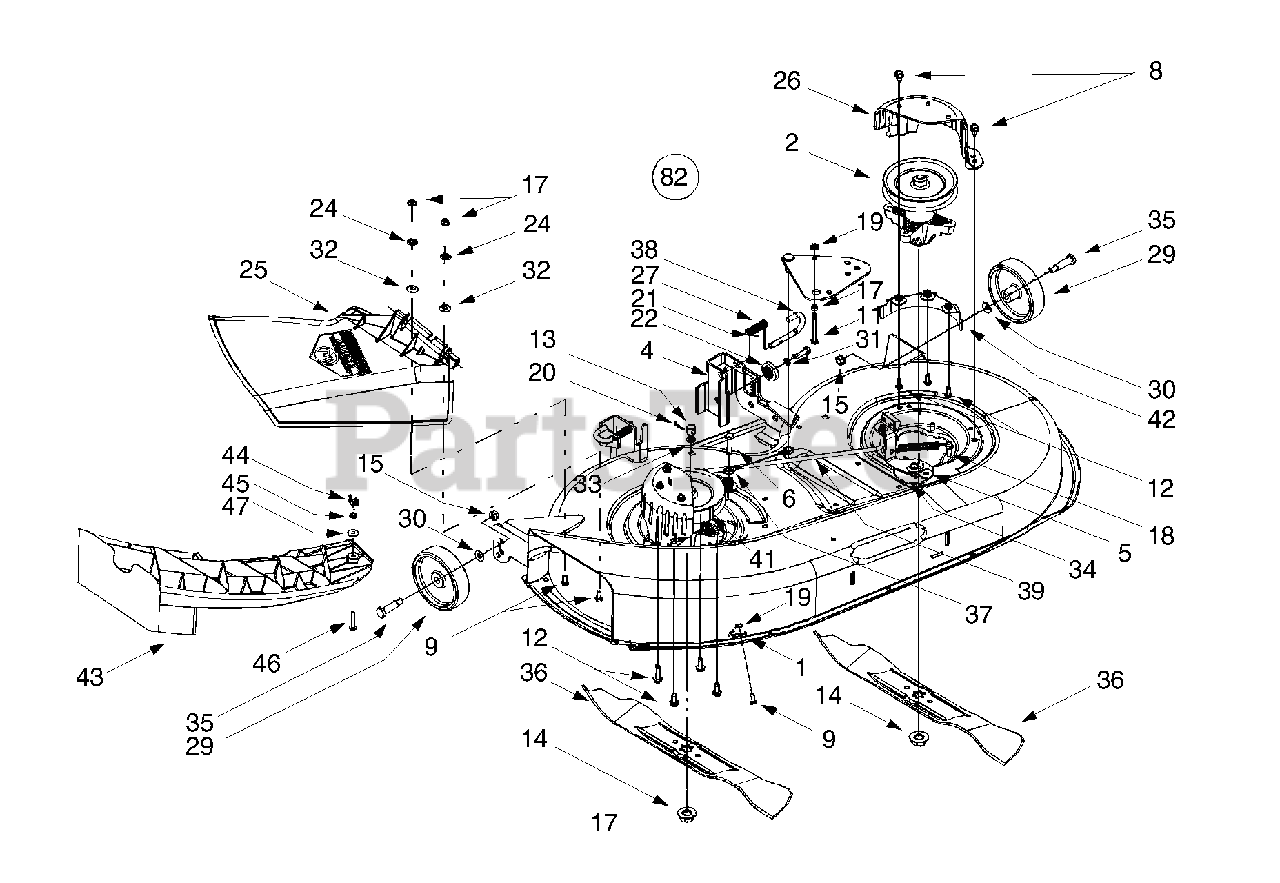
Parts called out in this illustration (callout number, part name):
1	Retainer Hook
2	Spindle Assembly, 5.75 Dia.
5	Deck Brake Assembly, 42-inch Decks
6	Hex Cap Screw, 3/8-16 x 1.5
8	Self-tapping Screw, 5/16-18 x .625
9	Hex Cap Screw, 1/4-20 x .62
11	Hex Cap Screw, 1/4-20 x 2.5
12	Self-tapping Screw, 5/16-18 x .75
13	Ferrule, 5/16-18
14	Hex Flange Nut, 5/8-18
15	Flange Lock Nut, 3/8-16
17	Hex Nut, 1/4-20
18	Hex Lock Nut, 5/16-18
19	Hex Flange Lock Nut, 1/4-20
20	Internal Cotter Pin, .072 x 1.12
21	Cotter Pin, 3/32 x 1.0
22	Deck Adjustment Gear
24	Push Nut. .25 x .5
25	Side Discharge Chute Assembly
26	Belt Cover
27	Compression Spring, .406 x .531 x 1.75
29	Deck Wheel, 5 x 1.38
30	Bell Washer, .401 x .87 x .063
31	Lock Washer, 5/16
32	Bell Washer, .265 x .75 x .062
33	Flat Washer, .344 x .688 x .065
34	Flat Washer, .320 x 3.0 x .125
35	Shoulder Screw, .498 x 1.53
36	Three-in-one Blade, Star Center, 21.23"
37	Bracket Cable, 5.35"
38	Deck Release Pin
39	Deck Brake Rod
43	Mulch Plug, 42-inch Decks
44	Wing Nut, 1/4-20
45	Hex Nut, 1/4-20
46	Hex Cap Screw, 1/4-20 x 1.0
47	Flat Washer, .28 x .74 x .063
